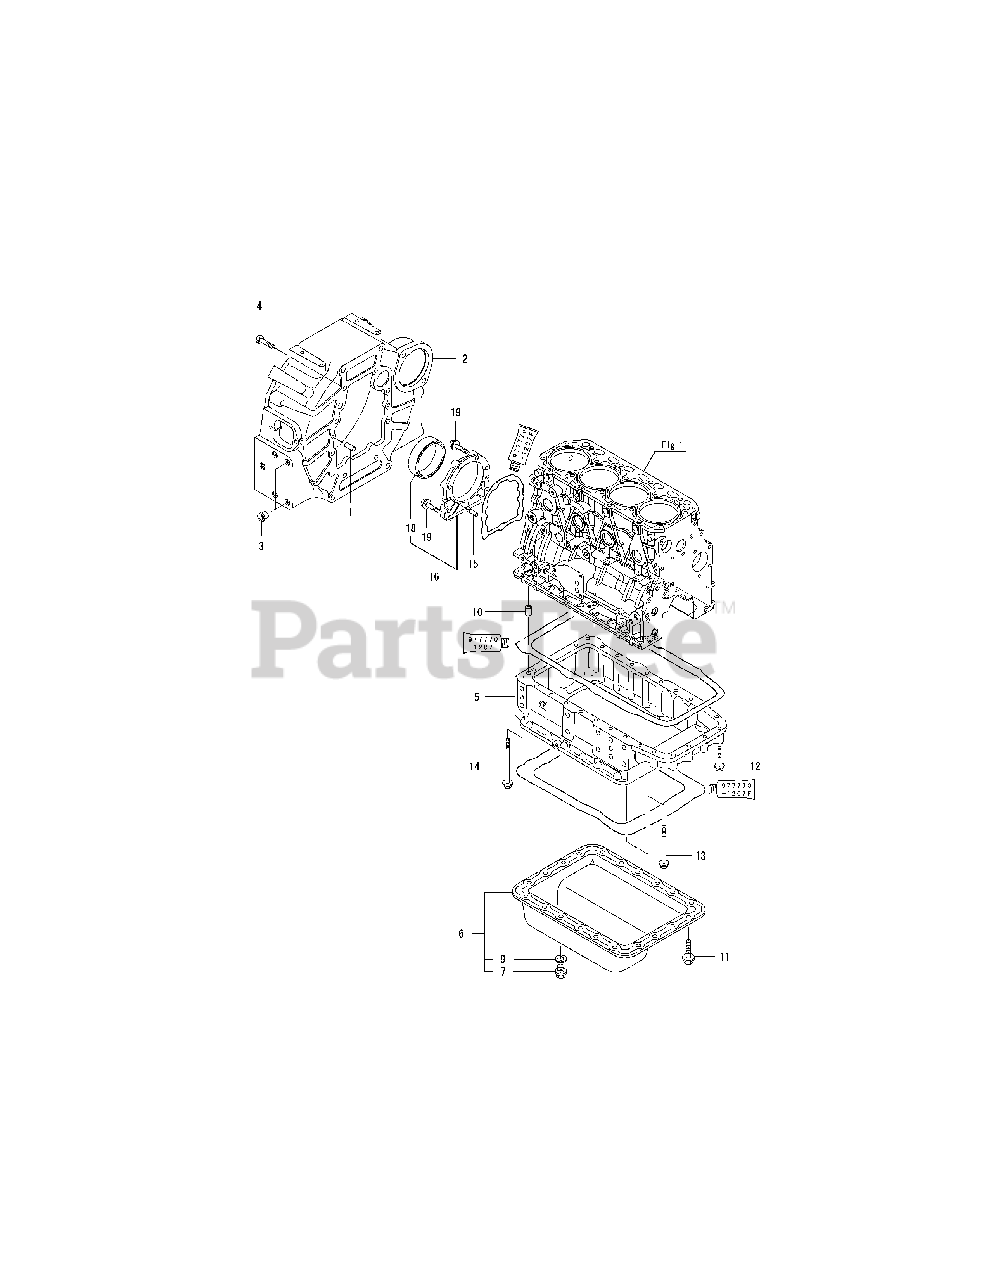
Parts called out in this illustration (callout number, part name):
2	HOUSING, FLYWHEEL
5	SUMP, LUB. OIL
6	COVER ASSY, OIL SUMP
11	BOLT M 8X 12 PLATED
12	BOLT M 8X 50 PLATED
13	BOLT M 8X100 PLATED
14	BOLT M 8X120 PLATED
16	CASE ASSY, OIL SEAL
